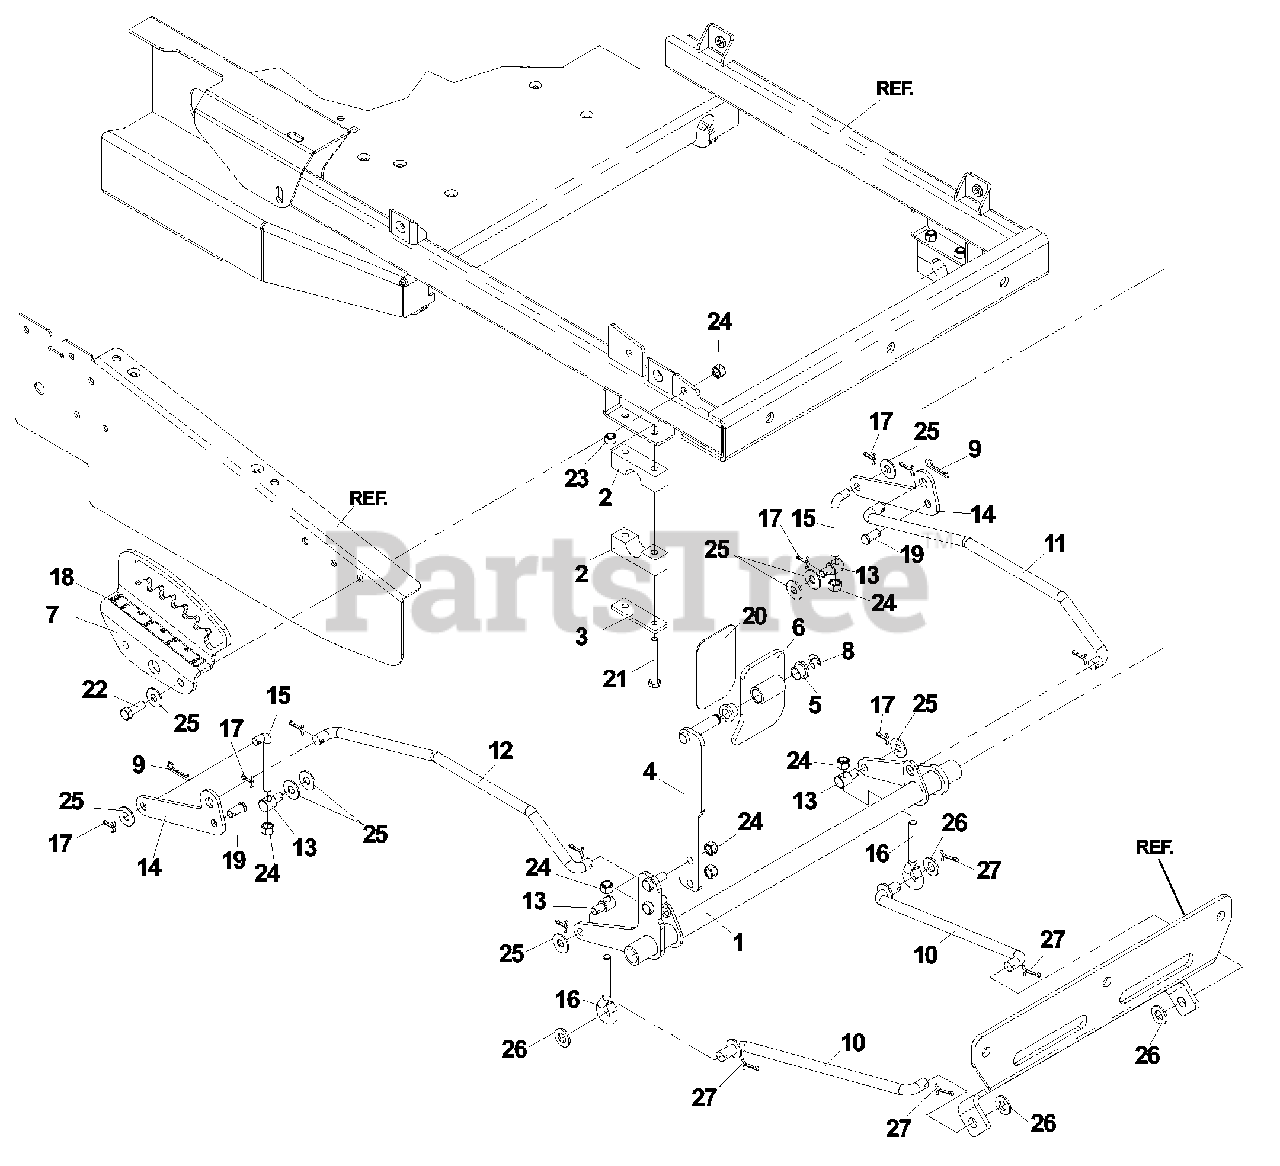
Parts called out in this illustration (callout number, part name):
1	CROSSSHAFT WLDMT.
2	PILLOW BLOCK
3	REINFORCEMENT BAR
4	LIFT ARM WLDMT.
5	BUSHING, NYLON FLANGED
6	FOOT PEDAL WLDMT.
7	HEIGHT PLATE
8	E-RING, 1/2"
9	PIN-HAIR COTTER
10	STRUT LINKAGE
11	LIFT LINKAGE, LEFT, PRIMARY
12	LIFT LINKAGE, RIGHT, PRIMARY
14	REAR BELLCRANK
15	LIFT LINKAGE
17	PIN, COTTER, 1/8 X 3/4
18	DECAL, CUTTING HEIGHT
19	CLEVIS PIN
21	HCS 5/16C X 2 1/2
22	HCS 3/8C X 1 1/4
23	NUT, 5/16C, NYLOC
24	NUT, 5/16C, NYLOC
25	WASHER, 3/8, FLAT
26	WASHER, 1/2 SAE
27	COTTER PIN, 5/32 X 1 1/8
